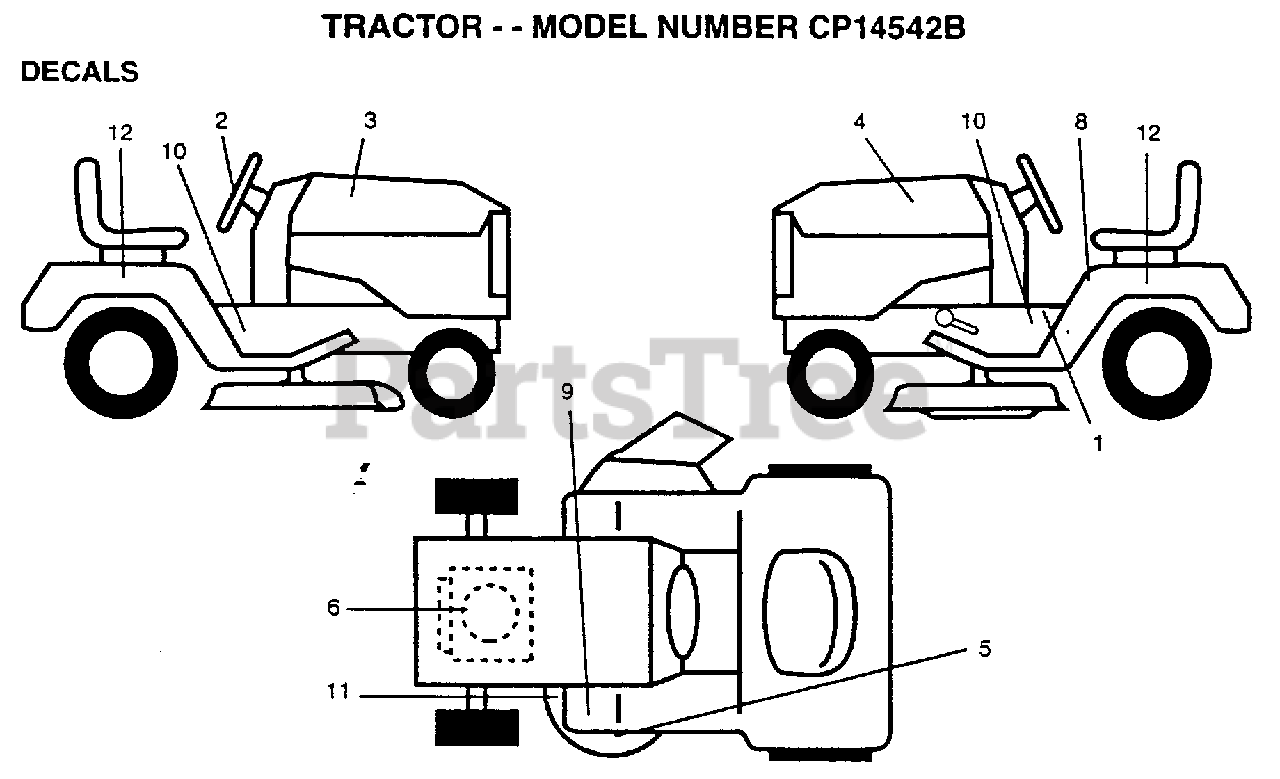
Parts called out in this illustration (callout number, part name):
3	DECAL.HD.RH.CP.
4	DECAL.HD.LH.CP.
6	DECAL, ENGINE
8	DECAL
10	CHASSIS DECAL
11	DECAL
12	DECAL.FEND.QUICK.
